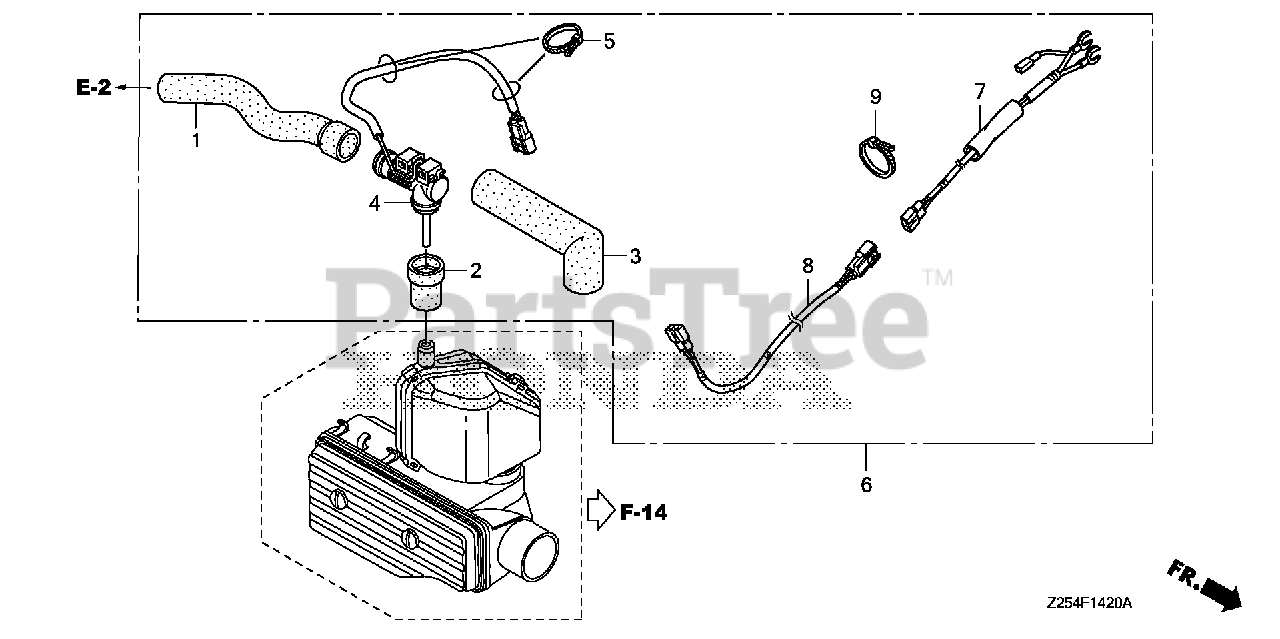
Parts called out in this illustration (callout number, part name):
1	TUBE A, BREATHER
2	TUBE B, BREATHER
3	INSULATOR, BREATHER TUBE
4	HEATER ASSY., BREATHER
5	BAND A, HARNESS (NATURAL)
6	HEATER KIT, BREATHER
7	SUB-WIRE ASSY.
8	WIRE ASSY., EXTENSION
9	BAND A, HARNESS (NATURAL)
